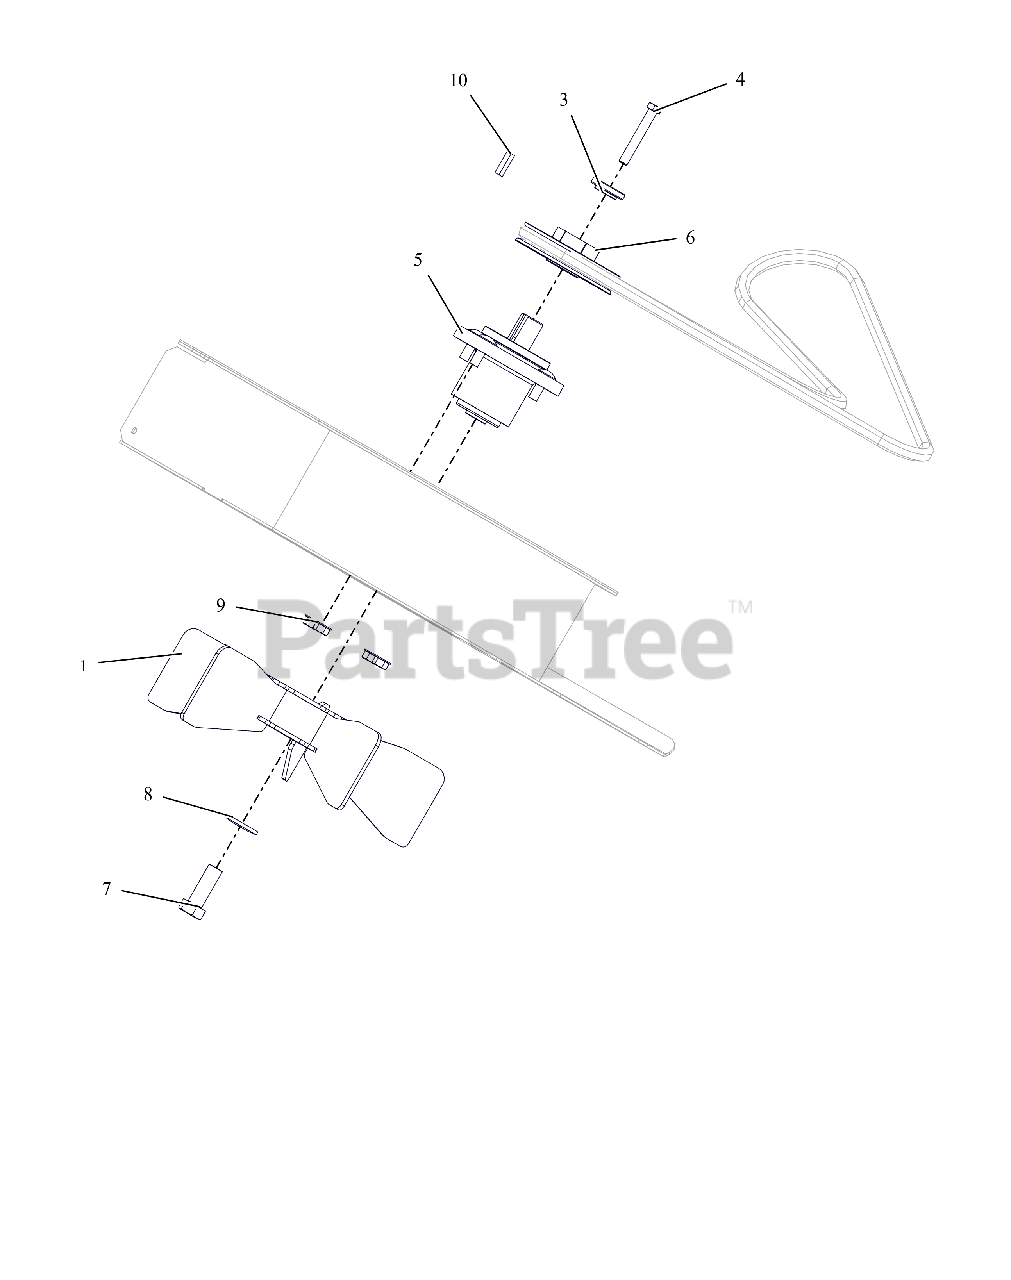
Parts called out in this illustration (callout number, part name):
1	IMPELLER, HD BLOWER
3	RETAINER, SHEAVE
4	BLT-HEX .38-16X2.50 GR8 YWZC
5	SPINDLE ASSY, SERVICE (BLOWER)
6	PULLEY, V-1.00"ID X 4.50" OD
7	BLT-HEX .62-18X1.75 GR8 YWZC
8	WSHR-BLVL .669X1.535X.138
9	@NUT-LK-TOP-FLG .38-16 YWZC
10	KEY, SQ .25X.25X1.00 RC 40-50
